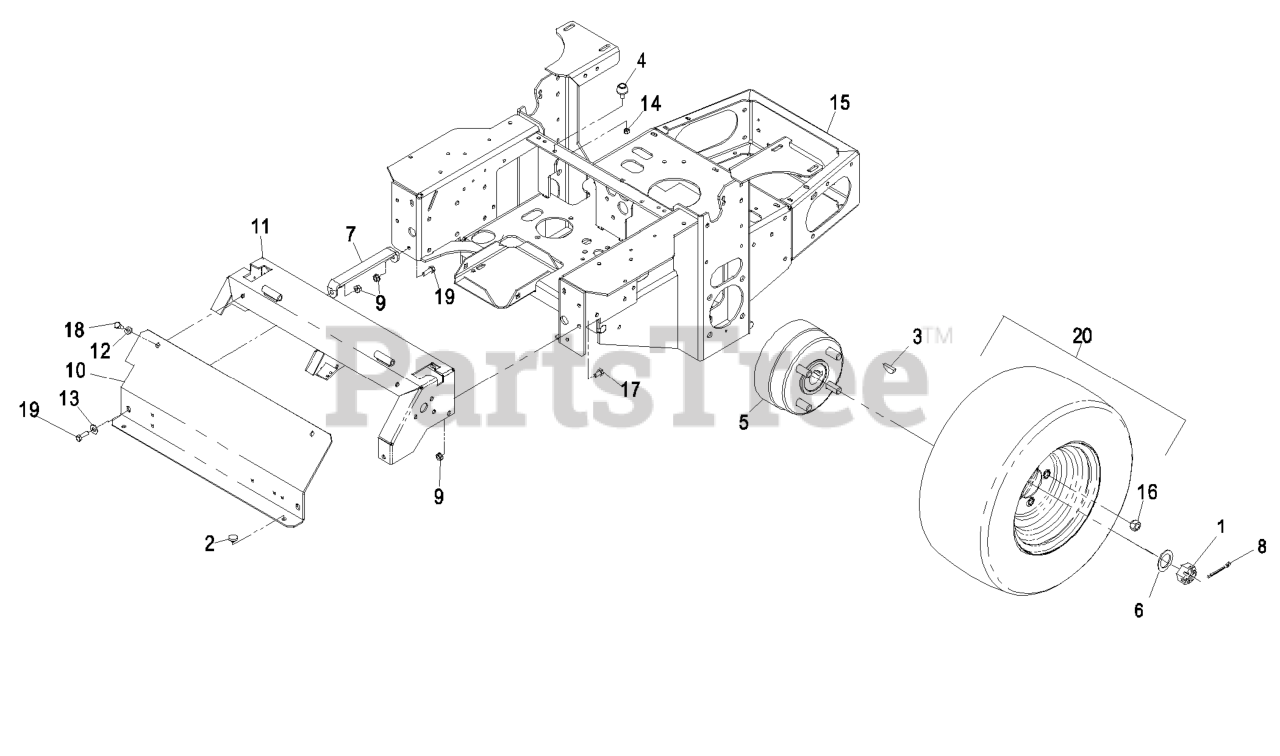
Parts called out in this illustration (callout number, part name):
3	KEY-WOODRUFF
4	BUMPER-RUBBER
5	WHEEL HUB ASM
6	WASHER-SPACER
7	BRACKET-PANEL, INSTRUMENT
8	PIN-COTTER
10	ASM,CONSOLE CT W/DECAL
11	ASM, CONSOLE W/DECALS
12	WASHER-PLAIN
13	WASHER-FLAT
15	WLD,MAINFRAME LCT
16	NUT-LUG
17	SCREW-HH
18	SCREW-HH
19	SCREW-HH
20	WHEEL AND TIRE ASM
